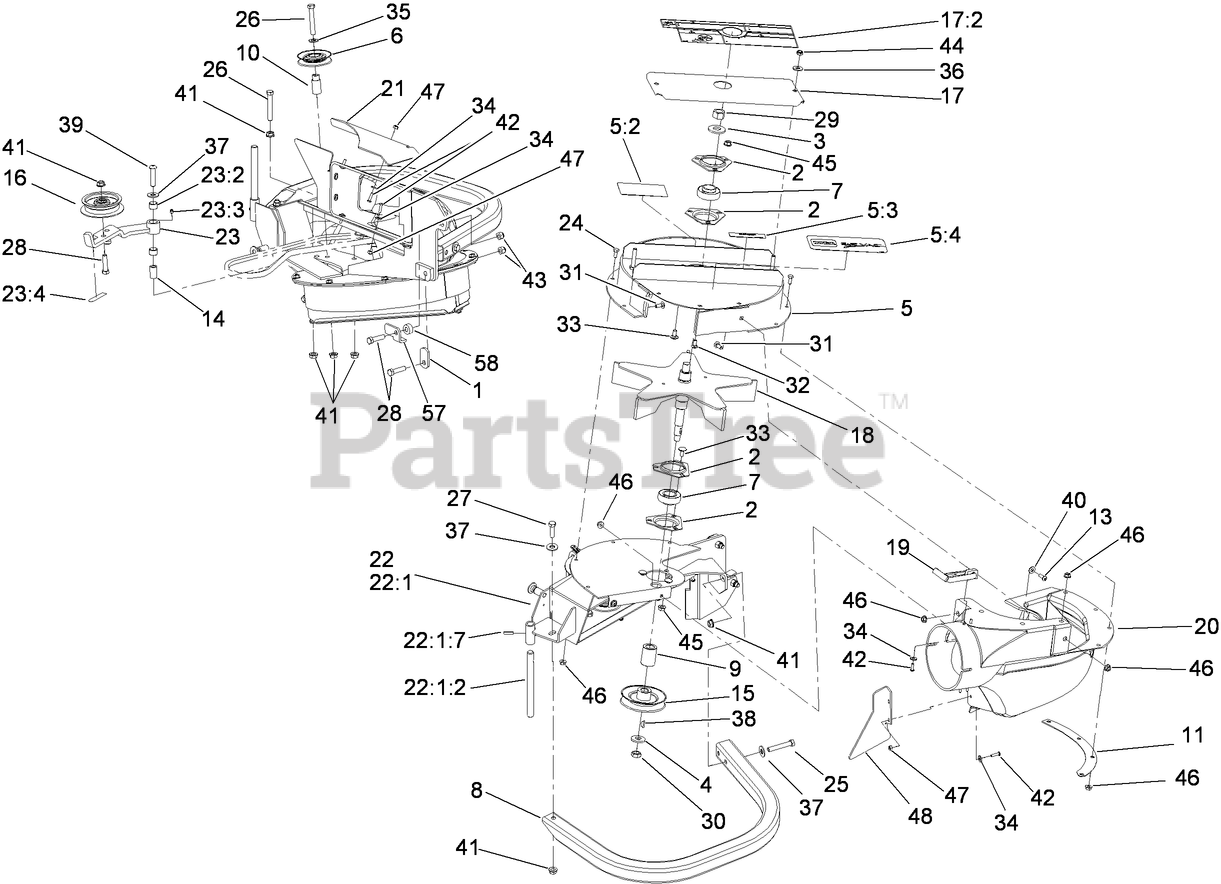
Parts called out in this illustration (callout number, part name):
1	LATCH-CATCHER, GRASS
2	HOUSING-FLANGE
3	WASHER-SPRING
4	WASHER-SPRING
5	UPPER HOUSING ASM
5:2	DECAL-WARNING
5:3	DECAL-COVER, MISSING
6	IDLER-INSIDE
7	BEARING
9	SPACER
11	PLATE-BACKING, BLOWER
13	SCREW-HSBH
14	BUSHING-PIVOT, IDLER
15	PULLEY
16	IDLER-FLAT
17	BEARING COVER ASM
17:2	DECAL-WARNING
18	IMPELLER
19	LATCH-RUBBER
20	CHUTE-BLOWER, SMALL
21	PLATE-BOTTOM
22	BLOWER MOUNT ASM
22:1	BLOWER-MOUNT
22:1:2	SHAFT-CATCHER, GRASS
22:1:7	PIN-ROLL
23	IDLER ARM ASM W/BUSHINGS
23:2	BUSHING
23:3	FITTING-GREASE
23:4	DECAL-WARNING
24	SCREW-HH
25	SCREW-HH
26	SCREW-HH
27	SCREW-HH
28	SCREW-HH
29	NUT-HEX
30	NUT-JAM
31	BOLT-CARR
32	SCREW-CARR
33	SCREW-CARR
34	WASHER-FLAT
35	WASHER-FLAT
36	WASHER-FLAT
37	WASHER-FLAT
38	KEY-WOODRUFF
39	SCREW-HSBH
40	WASHER-FLAT
41	NUT-HHF, WHIZ
42	SCREW-HSBH
43	NUT-LOCK, NI
44	NUT-LOCK, NI
45	NUT-HF
46	NUT-HF
47	NUT-LOCK, NI
48	PLATE-FILLER, REAR
57	LATCH-STOP
58	SPACER
